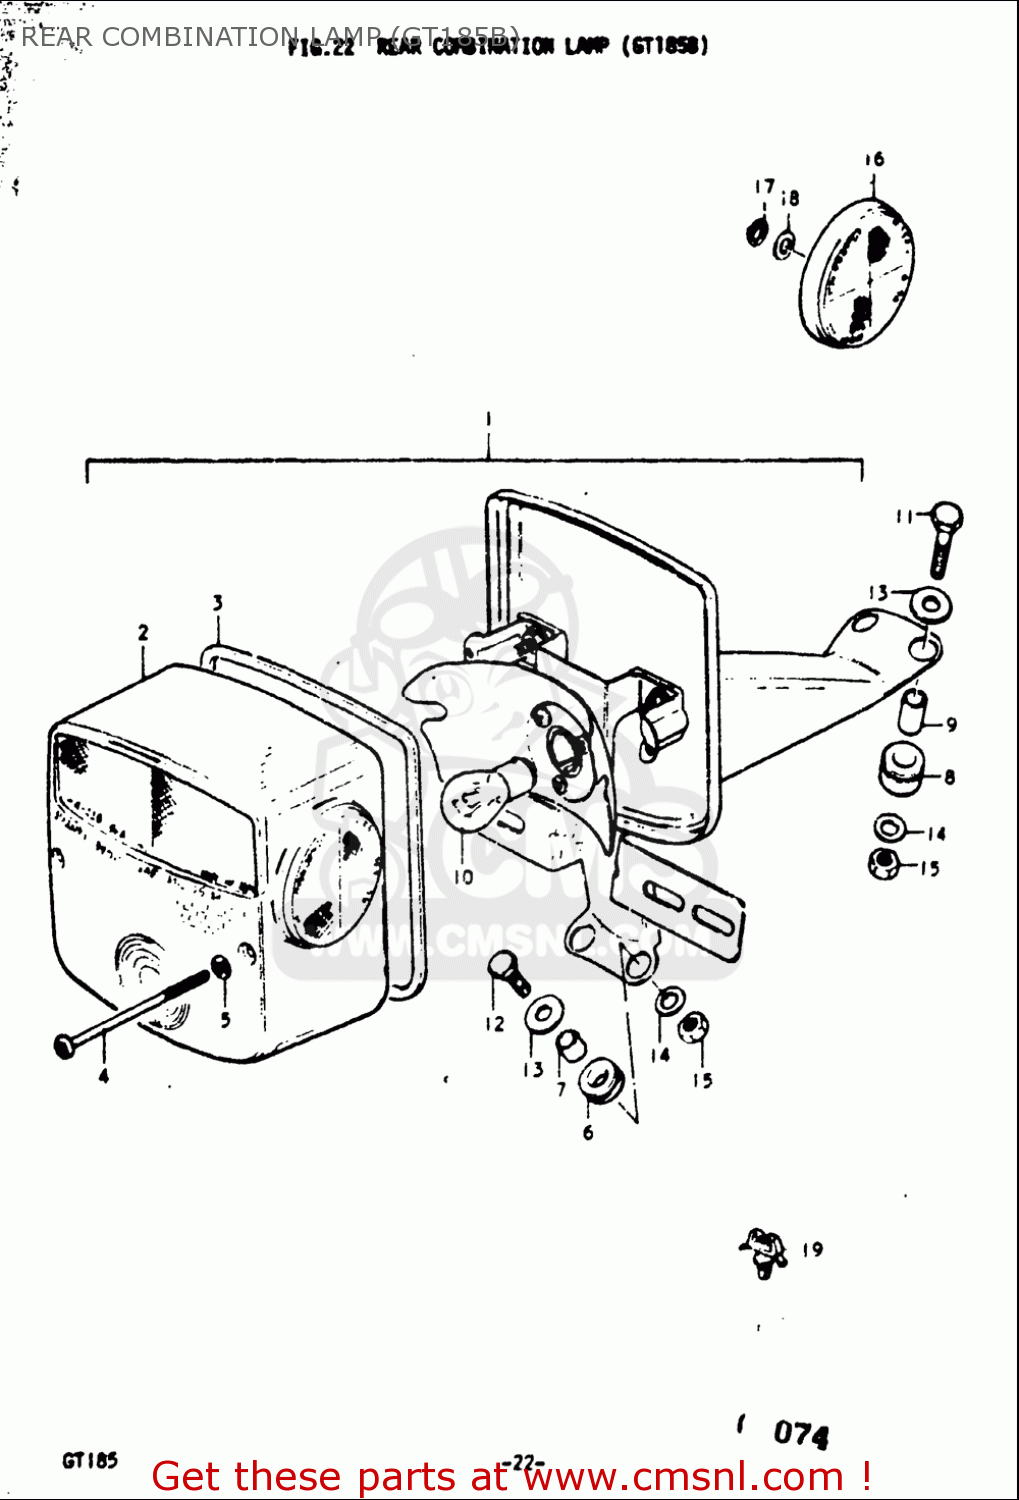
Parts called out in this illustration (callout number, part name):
2	LENS
3	GASKET (NAS)
5	GASKET (NAS)
6	CUSHION
7	SPACER
8	CUSHION
9	SPACER
10	BULB(12V23W)
11	BOLT
12	BOLT
13	WASHER(6.5X20X1.2)
14	WASHER
15	NUT
16	REFLEX REFLECTOR,FR
17	WASHER,LOCK
18	WASHER
